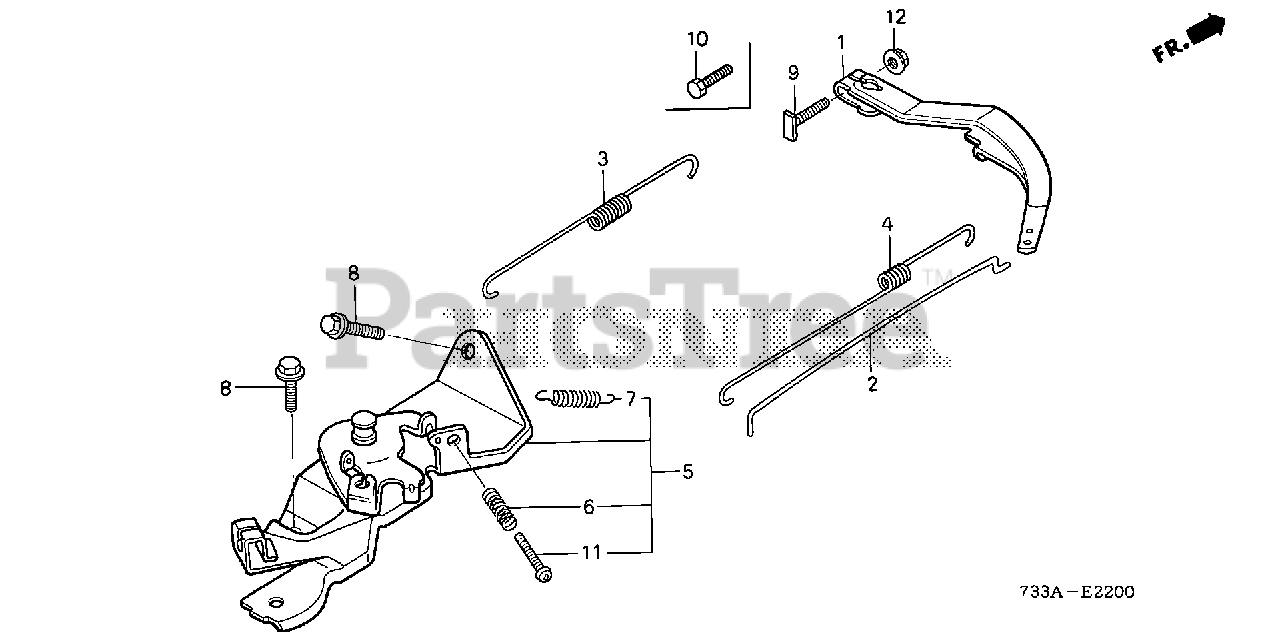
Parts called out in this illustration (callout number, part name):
1	ARM, GOVERNOR
2	ROD, GOVERNOR
3	SPRING, GOVERNOR
4	SPRING, THROTTLE RETURN
5	CONTROL ASSY.
6	SPRING, CONTROL ADJUSTING
7	SPRING, CABLE RETURN
8	BOLT, FLANGE (6X12) (CT200)
9	BOLT, GOVERNOR ARM
11	SCREW, PAN (5X28)
12	NUT, FLANGE (6MM)
